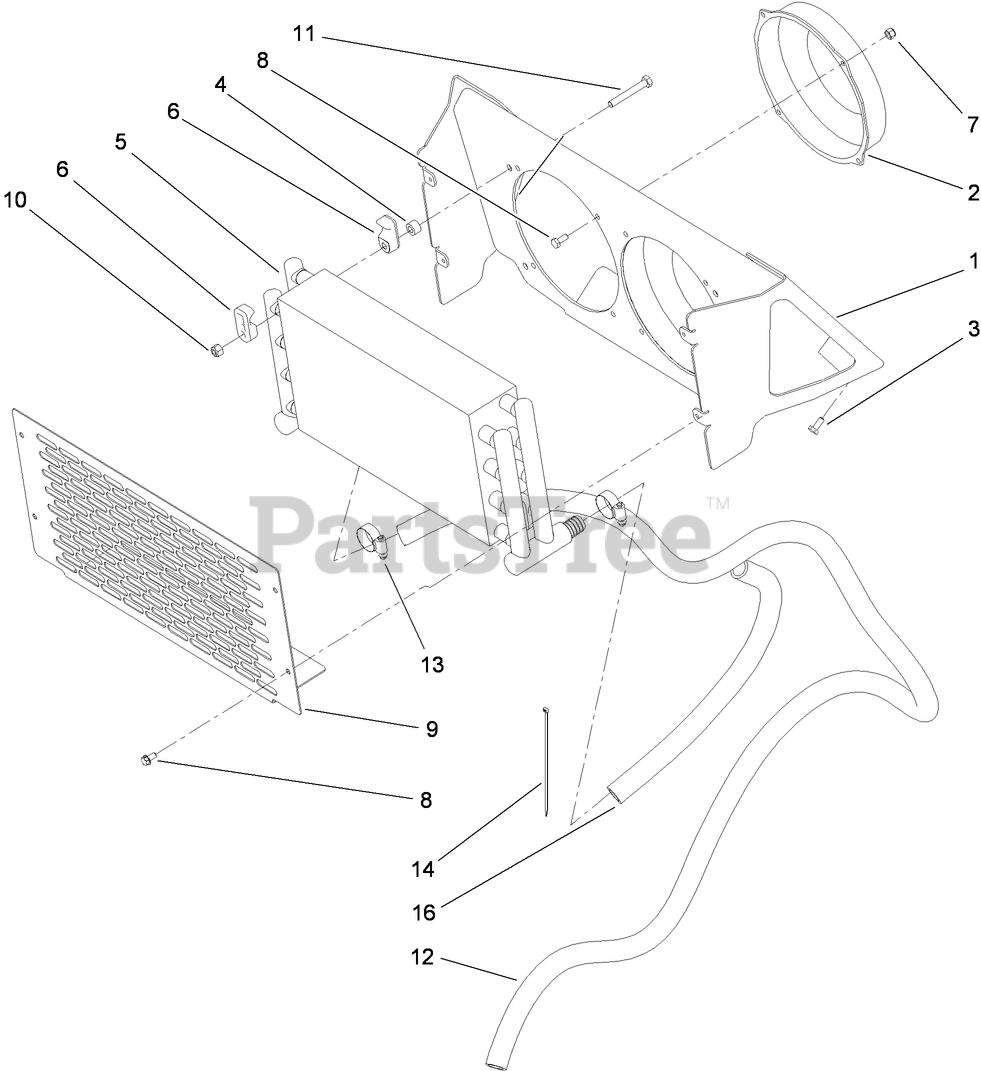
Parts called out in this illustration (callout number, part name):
1	MOUNT-COOLER
3	SCREW-HH
4	SPACER
5	COOLER-OIL
6	CLAMP-COOLER, OIL
7	NUT-LOCK, NI
8	SCREW-HWH
9	COVER-COOLER
10	NUT-LOCK, NI
11	SCREW-HH
12	HOSE-RETURN
13	CLAMP-HOSE
14	TIE-CABLE
16	HOSE-COOLER
